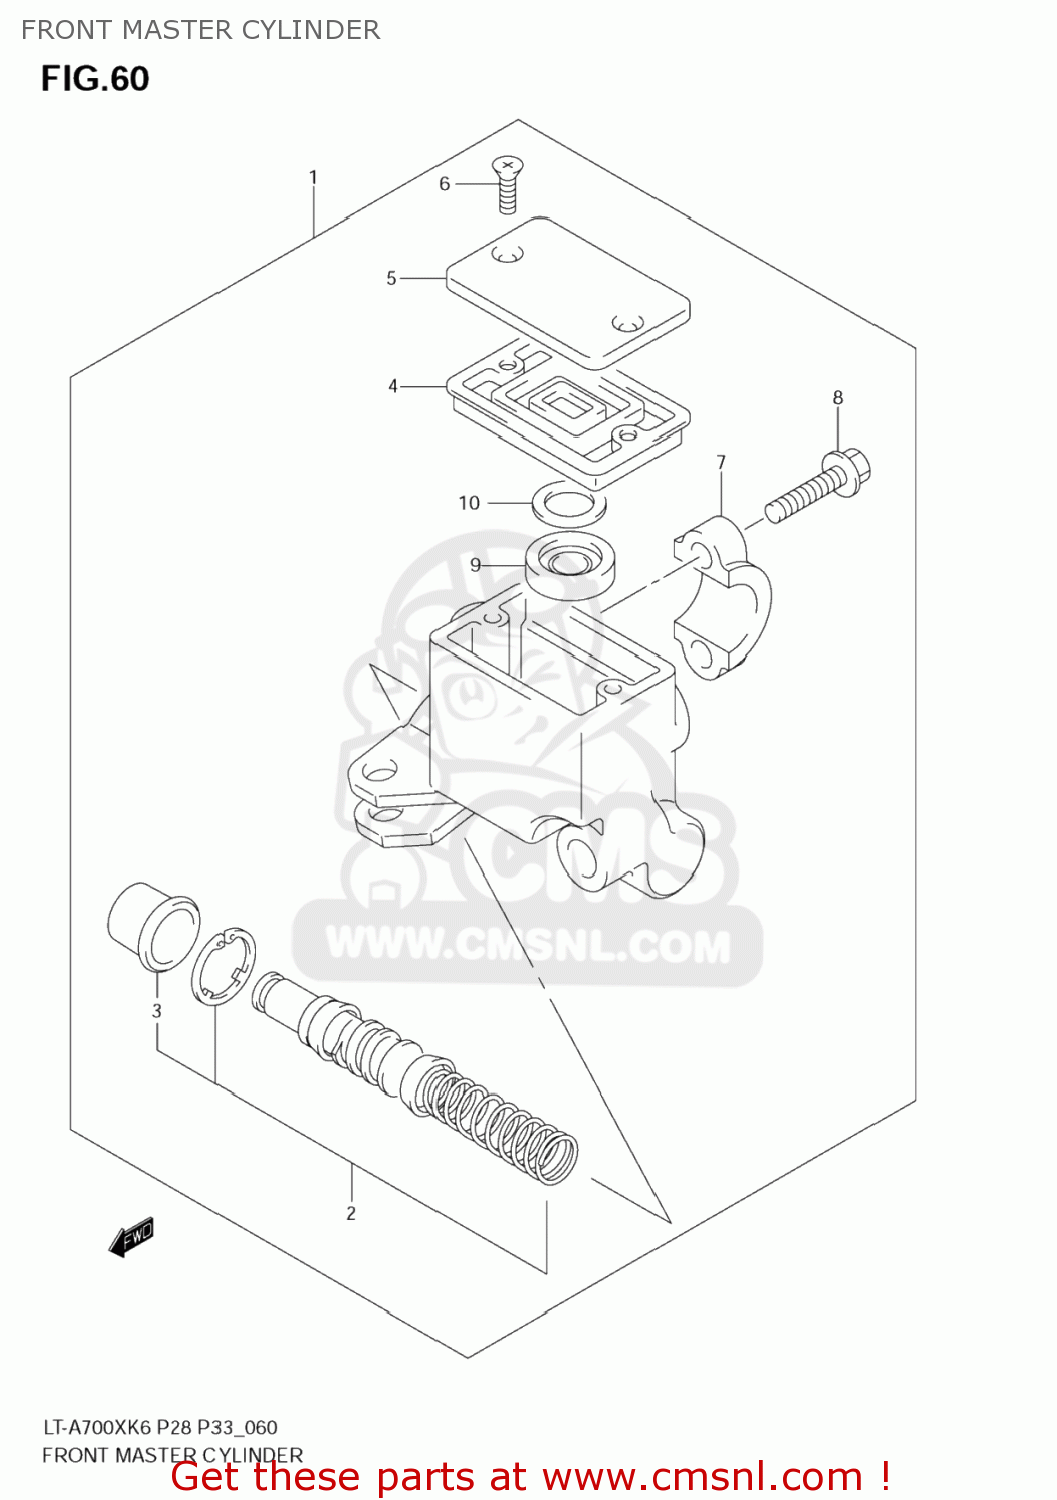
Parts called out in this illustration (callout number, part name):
1	CYLINDER ASSY,FR MASTER
2	PISTON & CUP SET
3	BOOT
4	DIAPHRAGM
5	CAP
6	SCREW
7	HOLDER
8	BOLT(6X22)
9	SEPERATOR
10	PLATE
